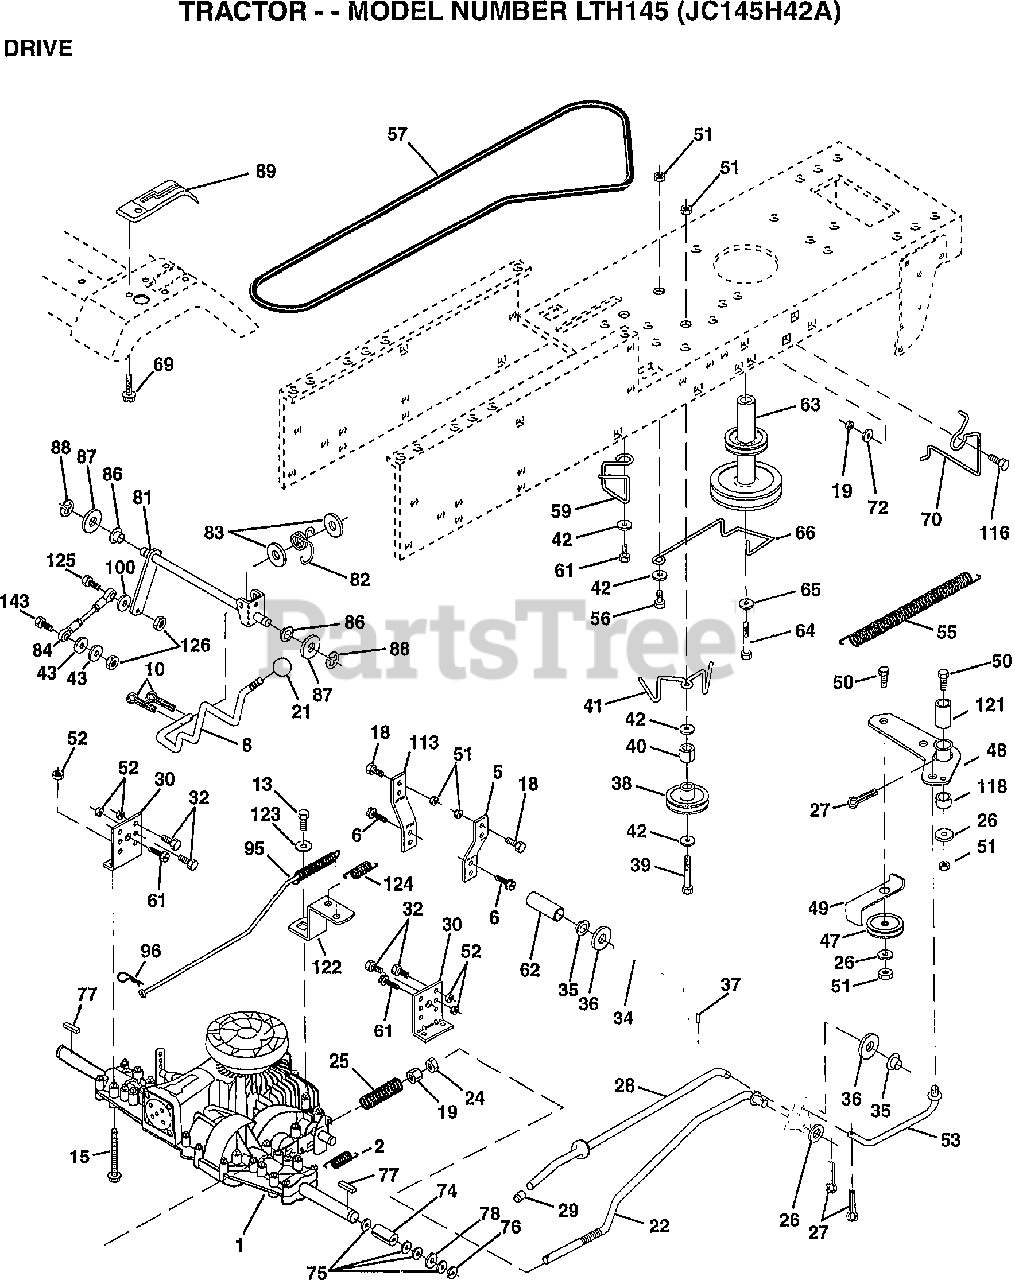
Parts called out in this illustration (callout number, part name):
1	TRANSAXLE, PEERLESS
6	SCREW THDROL 5/16-18 X 3/4 TYT
10	PIN COTTER 1/8 X 1 CAD
13	BOLT 1/4-28 GR 8 W/PATCH
15	BOLT HEX 5/16-18 GA 5
18	BOLT FIN HEX 3/8-16 X 1
19	LOCKNUT
24	NUT HEX JAM 3/8-16 UNC
26	WASHER 13/32 X 13/16 X 16 GA
27	PIN COTTER 1/8 X 3/4 CAD
32	BOLT, HEX 5/16-18 X 3/4
36	WASHER 21/32 X 1 X 16 GA
39	BOLT FIN HEX 3/8-16 X 2-3/4
42	WASHER
50	BOLT HEX HD 3/8-16 X 1-1/2
51	NUT, CROWNLOCK 3/8-16
52	LOCKNUT, CROWN 5/16-18
56	BOLT, HEX 3/8-16 X 1-1/4
61	SCREW THDROL 3/8-16X3/4 TY-TT
64	BOLT HEX
65	WASHER LOCK HVY HLCL SPR 7/16
72	WASHER 13/32 X 1-1/4 X 12 GA
76	E-RING #5133-75
81	SHAFT ASM CROSS HYDRO 18 " TIRES
83	WASHER 17/32 X 3/4 X 16 GA
84	"ROD TIE 18"""
87	WASHER 21/32 X 1-1/4 X 16 GA
88	RING CLIP #5304-62
100	WASHER 11/32 X 3/4 X 16 GA
116	BOLT RDHD SQ NECK 3/8-16 X 1.25
123	WASHER 8/32 X 5/8 X 16 GA
125	BOLT FIN HEX 5/16-18 X 1
